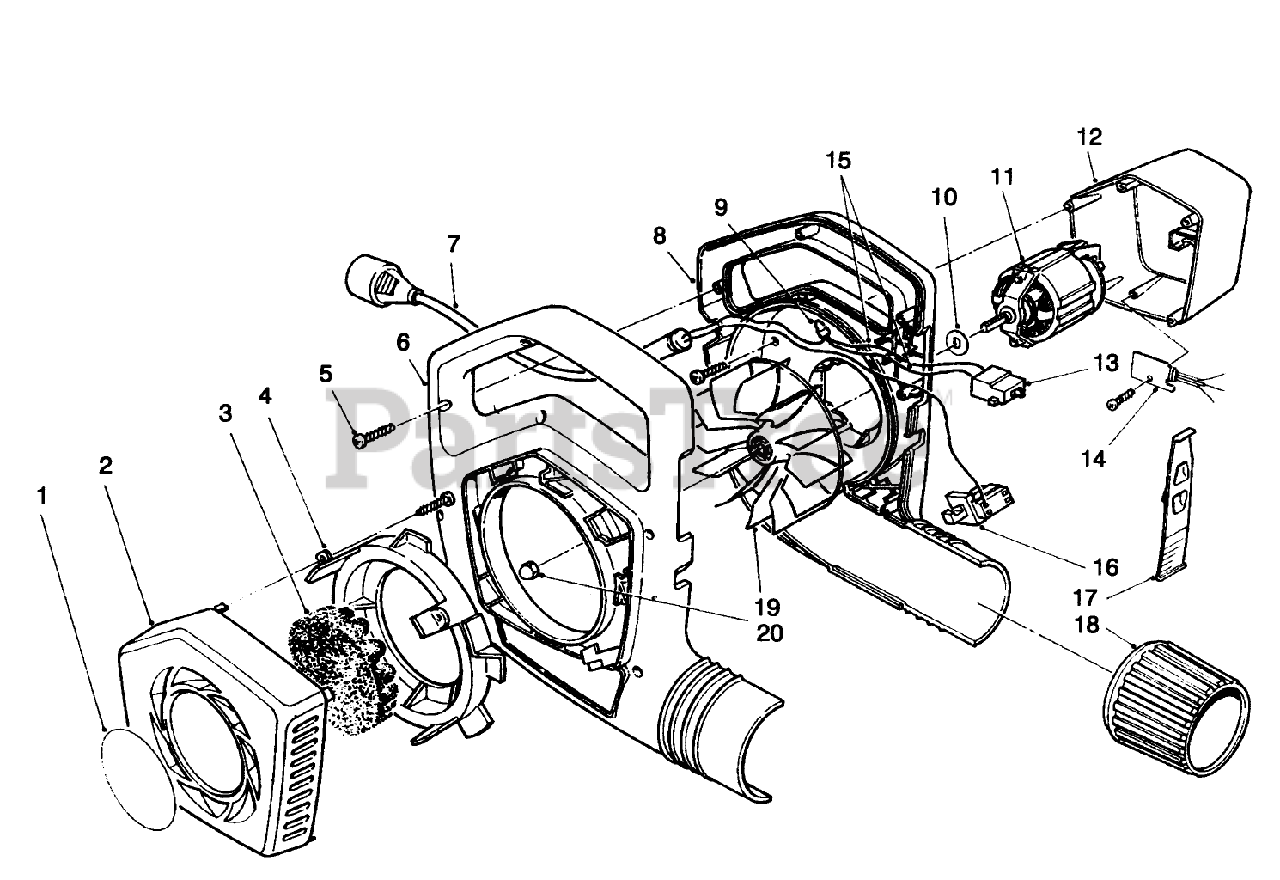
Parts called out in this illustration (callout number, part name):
1	DECAL, COVER
2	INTAKE COVER, 850 BV
3	CENTER FOAM
4	Ring-Coupling
5	Screw
6	Housing-Blower,R.H.
7	POWER SUPPLY CORD 9.5
8	BLOWER HOUSING, LH
9	Connector
10	WASHER, FAN
11	Motor-Blower
12	MOTOR COVER,850 HOTSTAM
13	Switch-2 Speed
14	DIODE ASSEMBLY
15	WIRE, 3 INCH
16	SWITCH-INTERLOCK
17	CAM SWITCH-HOT STAMPED
18	BV-OUTPUT COLLAR
19	IMPELLER, 850 BLOWER
20	NUT-HEX
